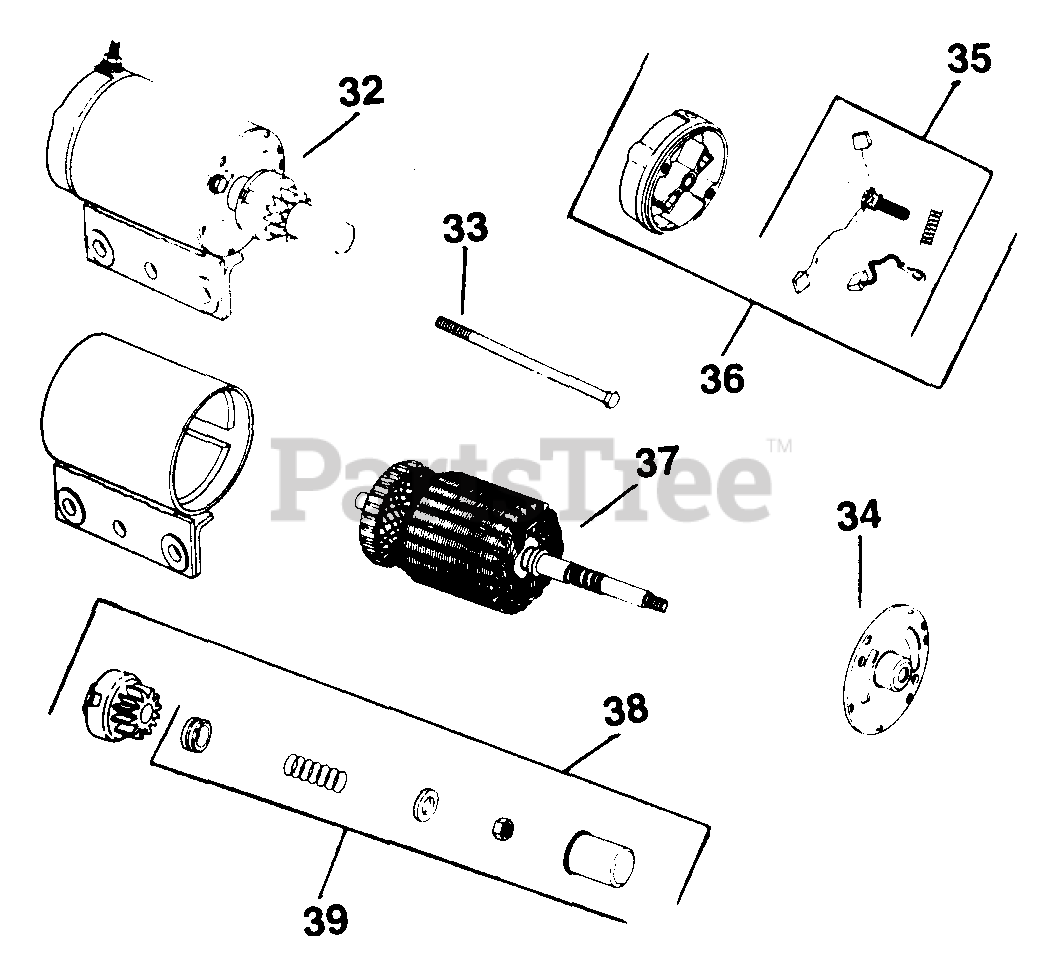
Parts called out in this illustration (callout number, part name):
32	STARTER - USE 45 098 07
34	CAP - USE 45 081 05
35	KIT - USE 82 755 28
36	CAP - DISCONTINUED
37	ARMATURE - DISCONTINUED
X-22-1-S	WASHER, SPRING LOCK 3/8"
